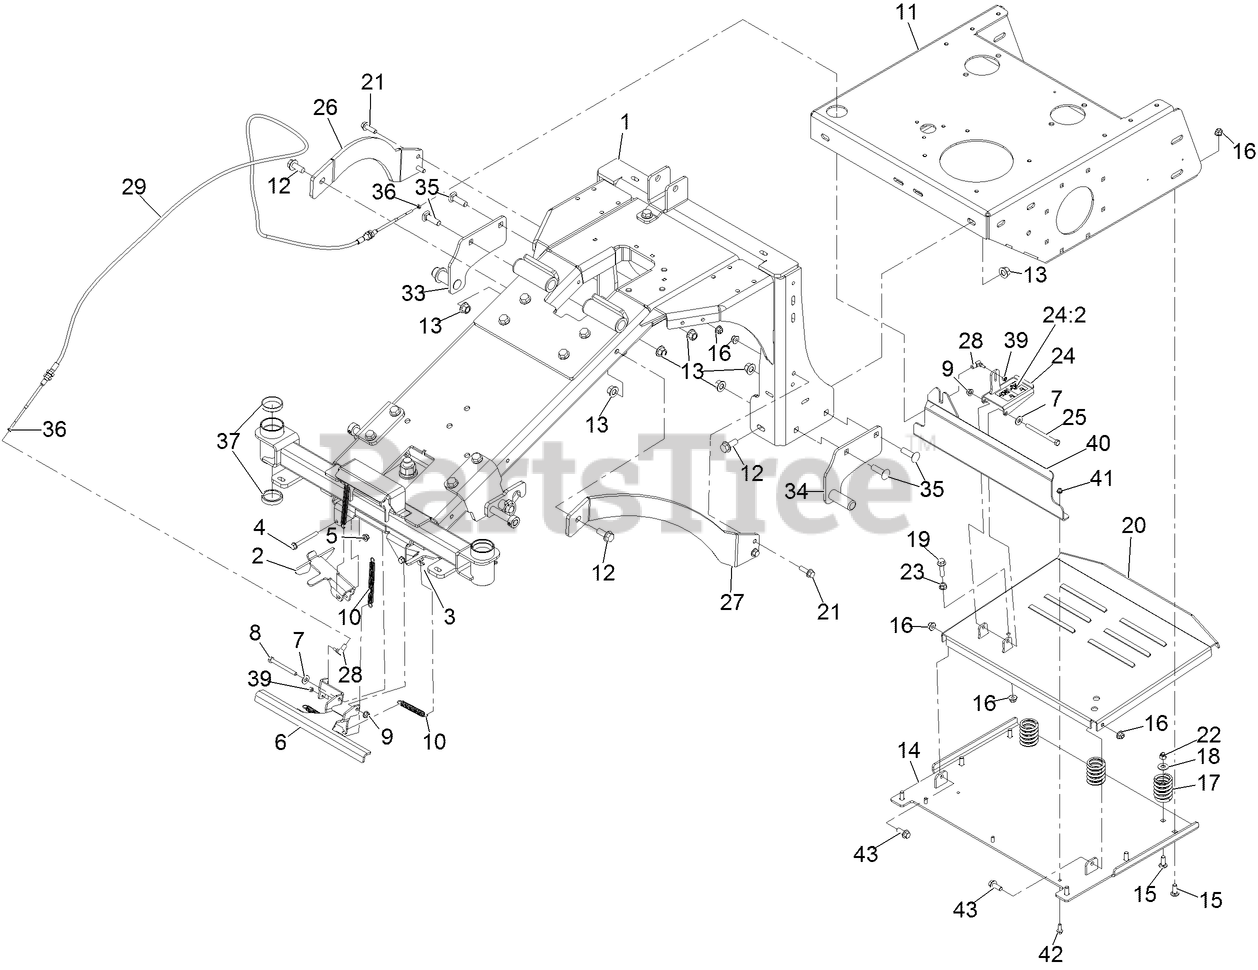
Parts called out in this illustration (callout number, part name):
1	Front Frame ASM
2	WING-CASTER RH
3	WING-CASTER LH
4	SCREW-HHF
5	Nut-Hex Flange
6	ARM-BODY, LCS
7	Washer-Flat
8	SCREW-HH
9	NUT-HF, NI
10	SPRING-EXTENSION
11	REAR FRAME ASM
12	SCREW-HHF
13	Nut-Lock 1/2-13
14	FRAME BASE
15	SCREW-CARR
16	NUT-HF, NI
17	SPRING-COMPRESSION
18	Washer-Flat
19	SCREW-HHF
20	WLD, FOOTPLATE, AE
21	SCREW-HHF
22	NUT-LOCK, NI
23	NUT-HEX FLANGE
24	PEDAL-FOOT
24:2	Decal-Lock, Caster
25	SCREW-HH
26	BRACE-FRAME, RH
27	BRACE-FRAME, LH
28	BALL JOINT-SS
29	ZPLUG LOCKING CASTER CABL
33	PIVOT-BRAKE, RH
34	PIVOT-BRAKE, LH
35	SCREW-CARR
36	Nut,Hex Jam Mch Scr,10-32,Sst
37	BEARING-CUP, TAPERED
39	Nut,NYL Lock,#10-32,ST/ST 18-8
40	SHIELD-HEAT, MUFFLER
42	SCREW-HHF
43	SCREW-HHF 3/8-16 X 1
